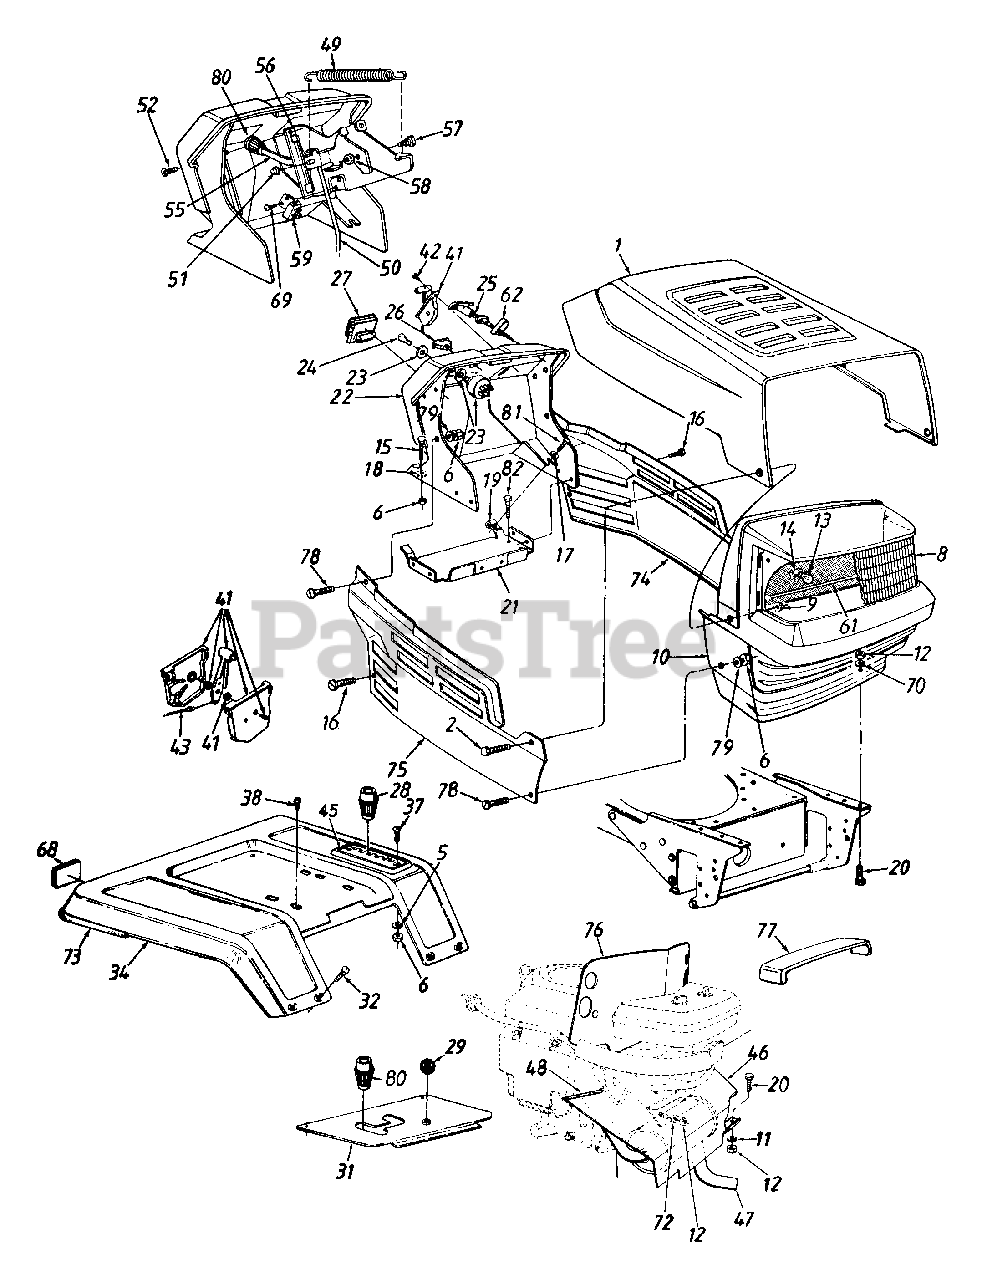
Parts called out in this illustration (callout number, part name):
5	L-Wash. 1/4" I.D.
6	Hex Nut 1/4-20 Thd.
8	Headlight Lens
9	Flange L-Nut 1/4-28 Thd.
10	Grille
11	L-Wash. 5/16" I.D.
12	Hex Nut 5/16-18 Thd.
13	Lamp
14	Socket
15	Carriage Bolt 1/4-20 x 1.0" Lg.
16	Hex Wash. Hd. TT-Tap Scr. 1/4-20 x .5" Lg.
17	Fl-Wash. .281" I.D. x .73" O.D.
18	Bolt Retainer 1/4" I.D.
19	Speed Nut 1/4-20 Thd.
20	Hex Bolt 5/16-18 x .75" Lg.
23	Ignition Switch
24	Ignition Key
25	Choke Control
26	Light Switch
27	Ammeter
28	Shift Knob
31	Shift Cover
32	Carriage Bolt 1/4-20 x .5" Lg.
38	Hex Wash. Hd. AB-Tap Scr. 5/16 x .75" Lg.
41	Throttle Box Ass'y.
42	Truss Mach. AB-Tap Scr. #10 x .5" Lg.
43	Throttle Control Wire
45	6-Speed Selector Plate
46	Front Heat Shield
47	Muffler
48	Trim Strip 12" Lg.
49	Ext. Spring 5.06" Lg
50	Deck Control Rod
51	Speed Nut 1/4" Rod
52	Torx Mach. Scr. 1/4 x .62" Lg
55	PTO Lever
56	PTO Bracket
57	Shld. Bolt .437" Dia. x .162"
58	Hex L-Nut 5/16-18 Thd.
59	Safety Switch (PTO)
61	Grille Reflector Label
62	Retainer Clip
68	Reflector
69	Hex Wash. Hd. B-Tap Scr. #10 x .38" Lg.
70	Fl-Wash. .344" I.D. x 1" O.D.
72	Spec. L-Wash. 5/16" I.D.
73	Trim Strip 81" Lg.
77	PVC Foam
78	Pan Hd. Mach. Scr. 1/4-20 x .5" Lg.
79	Bell-Wash 1/4" I.D.
80	Small Shift Knob
81	Hex TT-Tap Scr. 1/4-20 x .75" Lg.
82	Hex AB-Tap Scr. 1/4 x 62" Lg.
